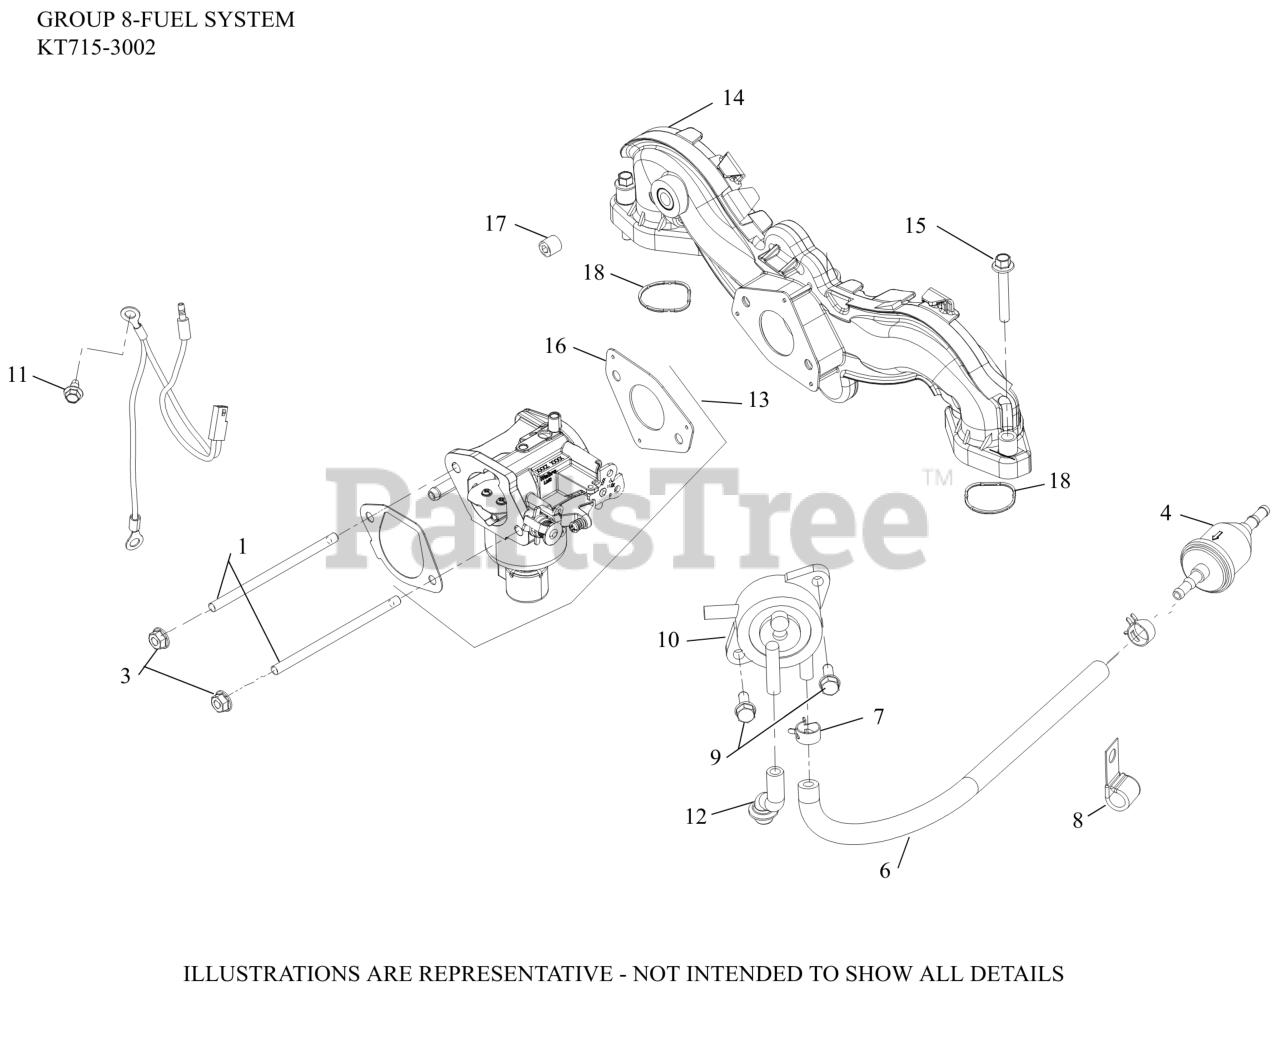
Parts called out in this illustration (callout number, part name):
3	NUT, FLG M6X1.0
4	FILTER,FUEL 51 MICRON (FUEL PUMP)
6	HOSE,LW PERM.FUEL 24.00"-USE 25 111 81-S
7	SPRING CLAMP, HOSE
8	CLIP, CABLE
9	SCREW, TAP M6X1.7X18
10	PUMP, FUEL (PULSE)-(#2539326S)
11	SCREW, THREAD FORMING
12	HOSE, PULSE PUMP(STEEL COVERS)
13	KIT,CARB(WALBRO)
14	KIT, INTAKE MANIFOLD-(#24164277S)
15	SCREW, FLG M6X1.0X40
16	GASKET, CARBURETOR
17	PLUG, CTSK PIPE 1/8"
18	O-RING, INTAKE PORT (PIM)
NI	KIT,REPAIR OVERHAUL(WALBRO)
NI	KIT,BOWL O-RING(WALBRO)
NI	KIT, HI ALTITUDE (5000 FT) 22MM
NI	KIT, SOLENOID REPAIR
NI	KIT, FLOAT REPAIR
